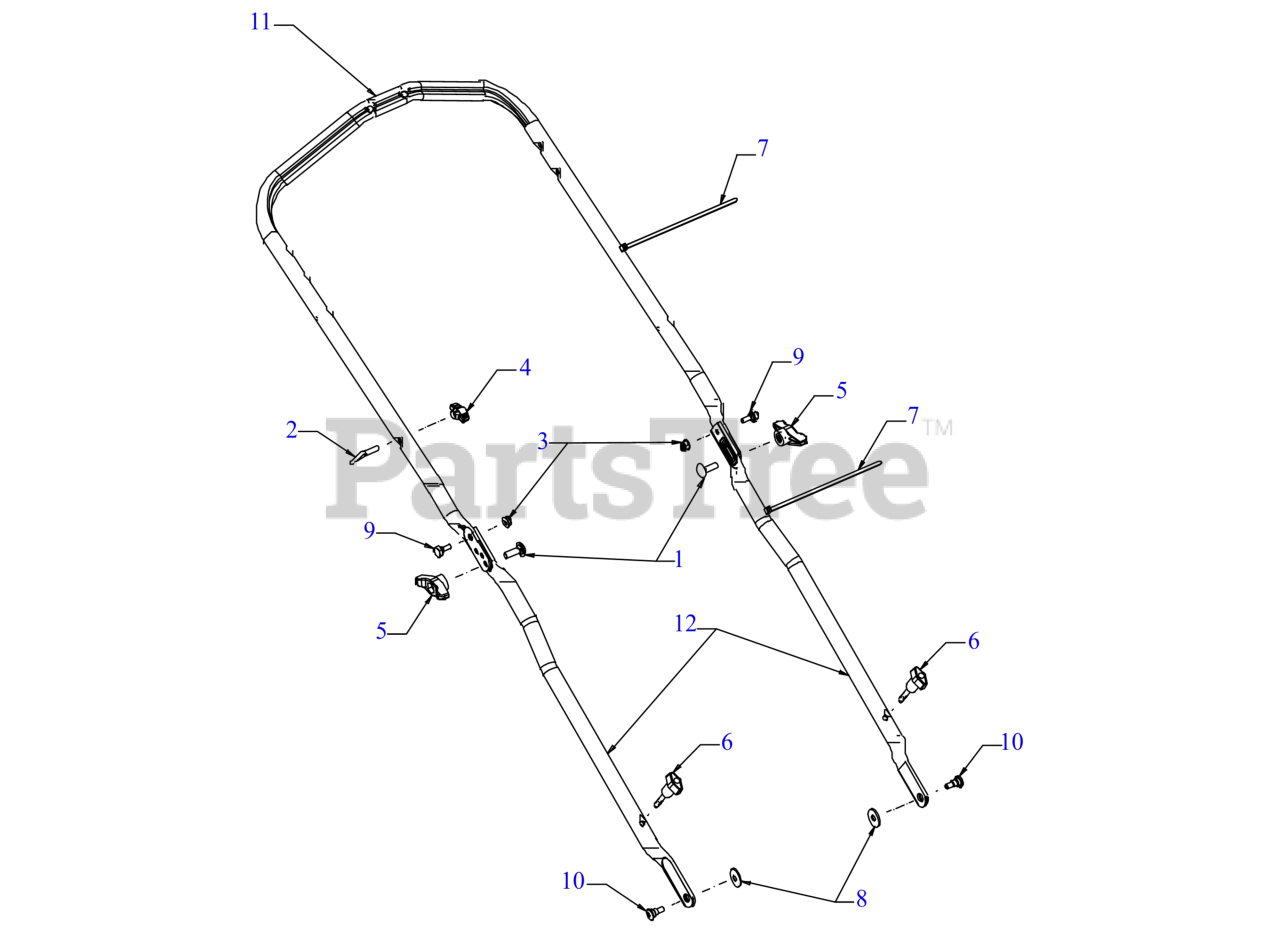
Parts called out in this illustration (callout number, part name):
1	SCREW 5/16-18 x 1.00 GR5
2	EYEBOLT 1/4-20
3	FLANGE LOCK NUT
4	HANDLE KNOB
5	STAR KNOB- YELLOW
6	WING KNOB 1/4-20
7	7" CABLE TIE
8	FLAT WASHER 344X1.00
9	SHOULDER SCREW
10	SHOULDER SCREW .450X .188X 1/4-20
11	UPPER ERGO HANDLE
12	LOWER HANDLE (EZ FOLD)
